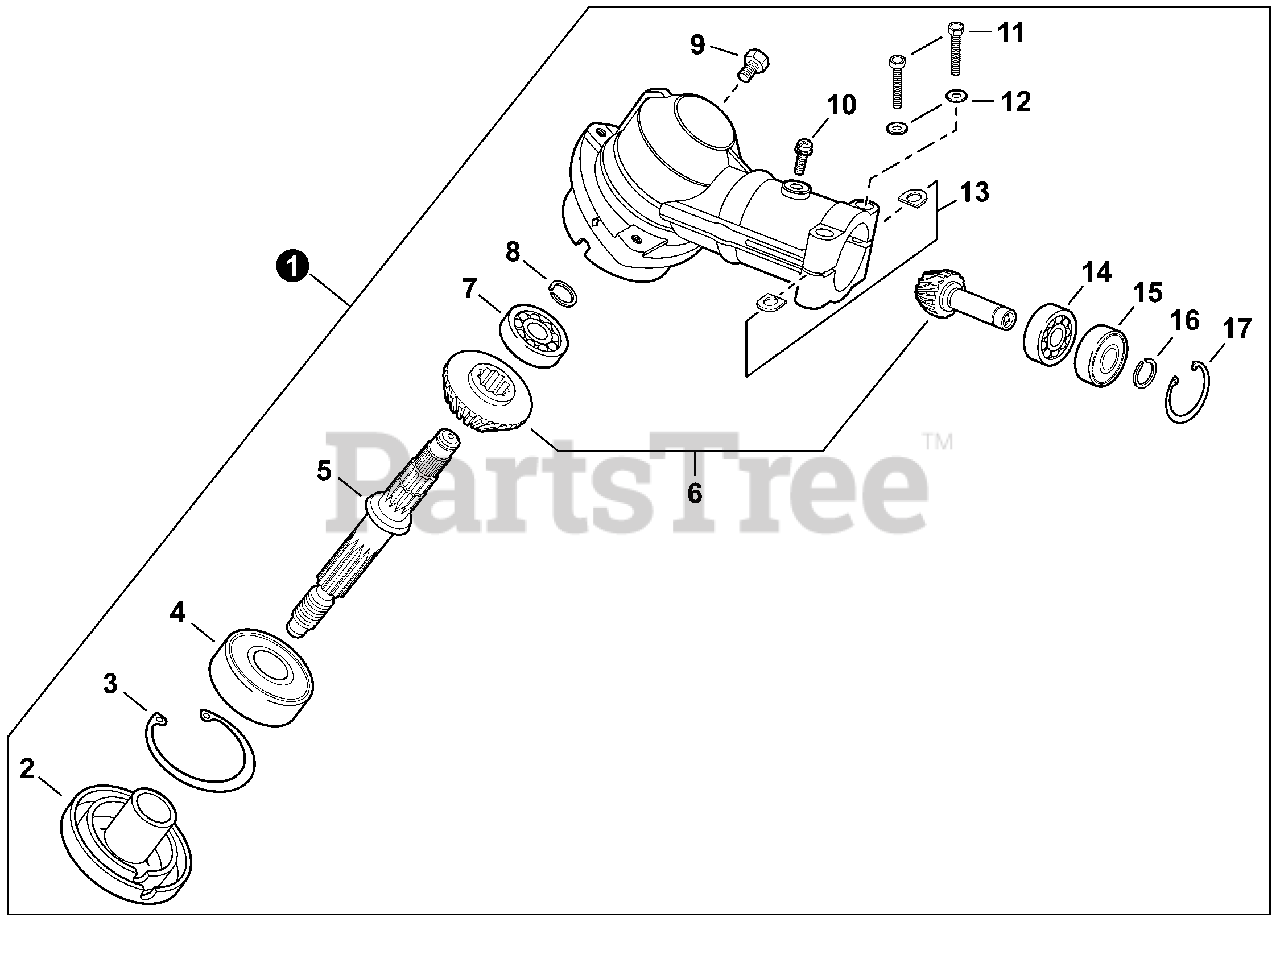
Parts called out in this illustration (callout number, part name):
1	GEAR CASE ASSY
2	PLATE, ADAPTOR - UPPER
3	RING, SNAP 42
4	BEARING, BALL 302
5	SHAFT, GEAR
6	GEAR SET
7	BEARING, BALL 629
8	RING, SNAP 12
9	BOLT M8×8
10	SCREW 5×12
11	BOLT 5×35 SP
12	WASHER, FLAT 5.5×10×0.8
13	D-WASHER
14	BEARING, BALL 6900
15	BEARING, BALL 6900-Z
16	RING, SNAP 10
17	RING, SNAP 22
